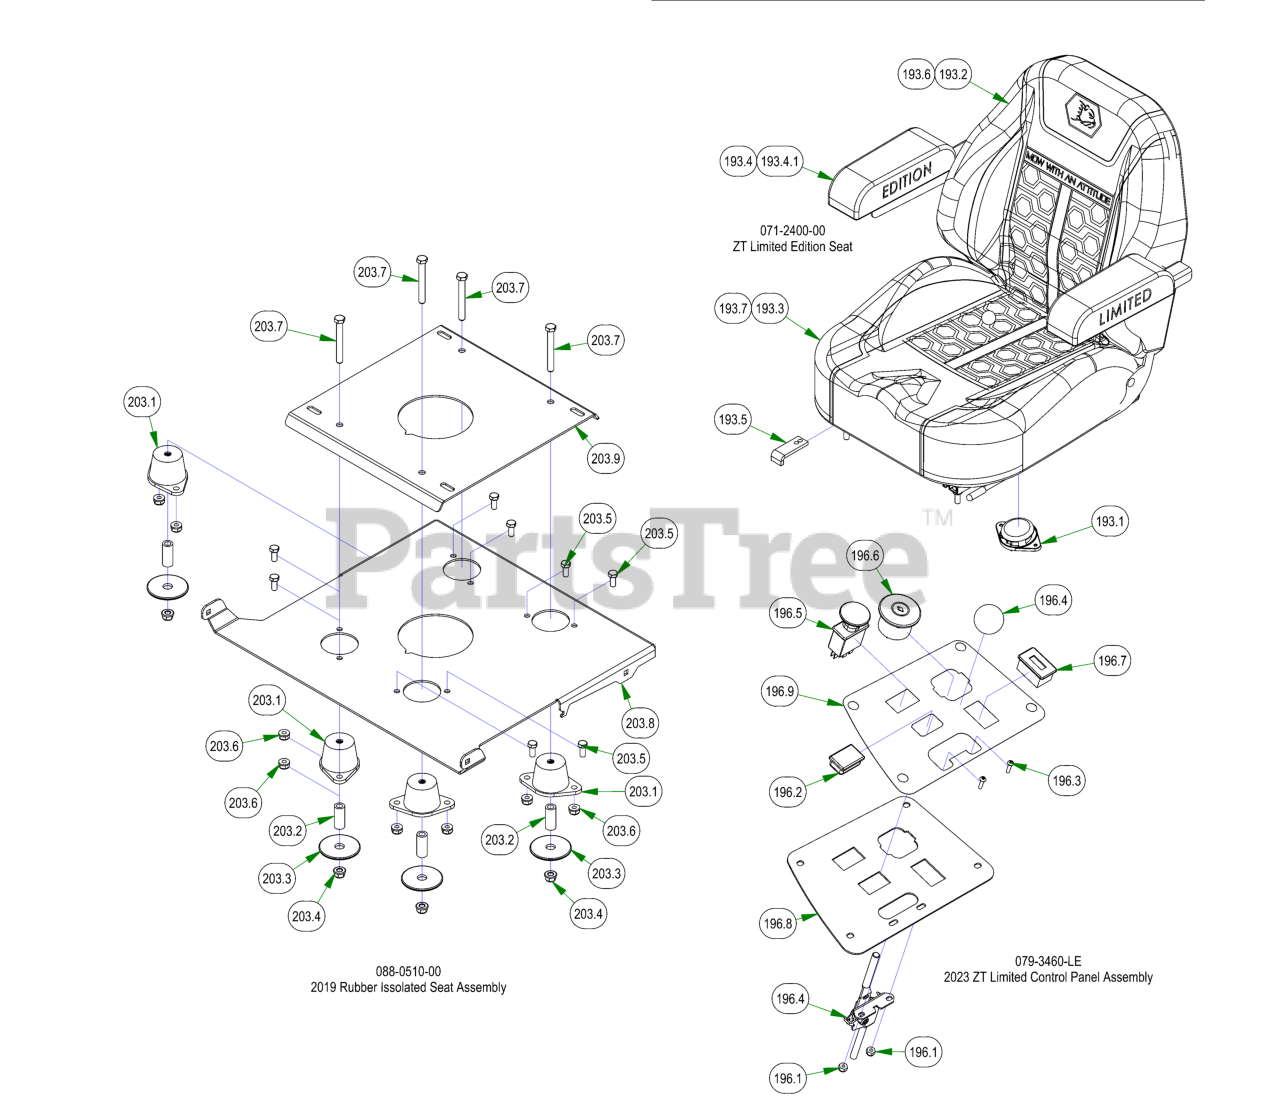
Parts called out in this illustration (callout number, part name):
193	ZT Limited Edition Seat
193.1	Seat Switch
193.2	Back Cover
193.3	Seat Cover
193.4.1	Pair of Pads Only for 071-2400-00
193.5	Seat Slide Stop
196	2023 ZT Limited Control Panel Assembly
196.1	10-24 Nylon Insert Locknut Zinc Orange Nylon
196.2	Light Plug
196.3	10-24 X 5/8 BS Button Head Bolt
196.4	Throttle Lever Assembly
196.5	PTO Engager
196.6	Ignition Switch
196.7	Tachometer
196.8	2014 ZT Control Panel
196.9	ZT Limited Edition Control Decal
203	2019 Rubber Issolated Seat Assembly
203.1	Vibration-Damping Mount 3/8"-16 Thread, 1.75"
203.2	2019 Outlaw Brake Handle Spacer .625 x 1.5
203.3	Snubbing Washer
203.4	3/8" Nylock Flange Nut
203.5	5/16" x 3/4" Hex Bolt
203.6	5/16-18 Nylon Flange Nut
203.7	3/8 x 3" Bolt
203.8	2019 Maverick Rubber Issolated Seat Bottom
203.9	2019 Maverick Rubber Issolated Seat Top
